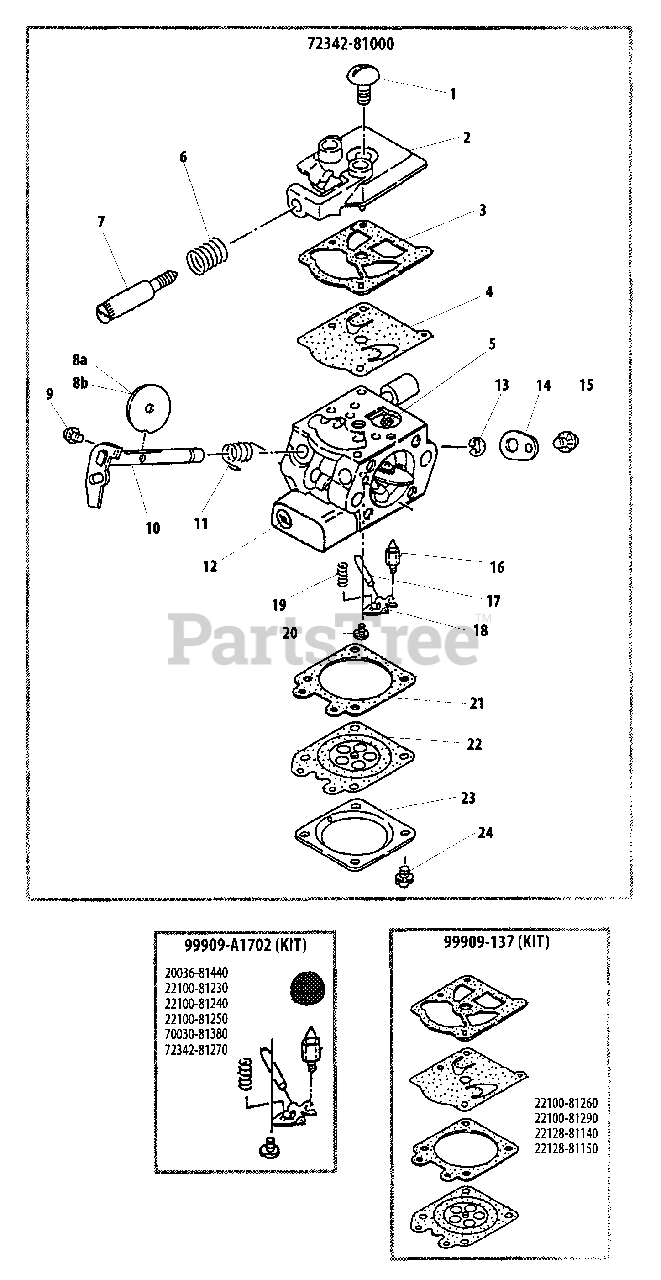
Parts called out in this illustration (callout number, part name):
1	SCREW, PUMP COVER
2	COVER, PUMP
3	GASKET, PUMP
4	DIAPHRAGM, PUMP
5	STRAINER
6	SPRING
7	SCREW, IDLE ADJUST
8A	VALVE, THROTTLE
8B	VALVE, THROTTLE
9	SCREW
10	SHAFT, THROTTLE
11	SPRING, RETURN
12	CAP, LIMITER
13	RING, RETAINING
14	TRIGGER, THROTTLE
15	SCREW
16	VALVE, INLET NEEDLE
17	PIN, METERING LEVER
18	LEVER, METERING
19	SPRING, METERING LEVER
20	SCREW, METERING LEVER PIN
21	GASKET, METERING
22	DIAPHRAGM, METERING
23	COVER, DIAPHRAGM
24	SCREW
72342-81000	CARBURETOR
99909-137	DIAPHRAGM/GASKET KIT
99909-A1702	REPAIR KIT
